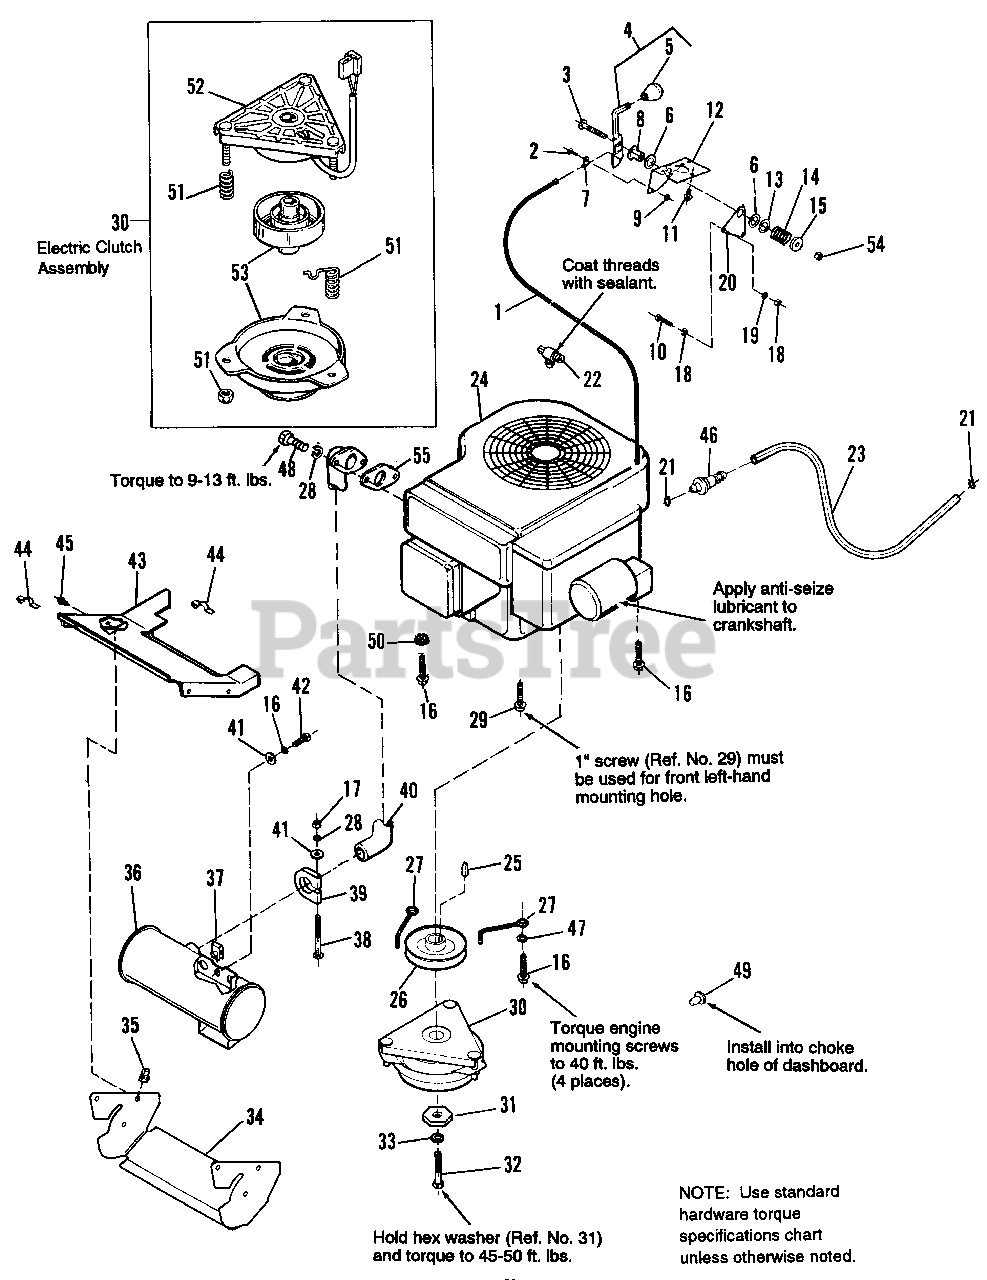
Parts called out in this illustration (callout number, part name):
1	CABLE, Throttle
2	SCREW, Trusshead, 10-32 x 1/2
3	CARRIAGE BOLT, 5/16-18 x 1-3/4
4	HANDLE, Throttle (Incl. Ref. No. 5)
5	KNOB, Throttle
6	WASHER, Nylon
7	CLIP, Bowden Wire
9	NUTASSY., 10-32
10	CAPSCREW, Hex, 1/4-20 x 1-1/2
11	SCREW, Plastite, 1/4-20 x 5/8
12	BRACKET, Throttle Mounting
15	WASHER, Plain, 5/16
16	SCREW, Hex, Washer Hd., Taptite, 3/8-16 x 1-1/2
17	NUT, Hex, Full, 5/16-18
18	NUT, Hex, Full, 1/4-20
19	LOCKWASHER, 1/4
20	PLATE, Spring
21	CLAMP, Hose
22	VALVE, Oil Drain
23	HOSE, Fuel, 38" Long
24	ENGINE, Briggs & Stratton
25	KEY, Hi-Pro
26	PULLEY ASSY.
28	LOCKWASHER, 5/16
29	SCREW, Hex, Washer Hd., Taptite, 3/8-16 x 1
30	ELECTRIC CLUTCH (Incl. Ref. Nos. 51-53)
31	WASHER, Hex
32	CAPSCREW, 7/16-20 x 2-1/2
33	LOCKWASHER, 7/16
34	DUCT, Lower Muffler
35	PAL NUT, 1/4-20
36	MUFFLER ASSY.
37	PAL NUT, 5/16-18
38	CARRIAGE BOLT, 5/16-18 x 2-3/4
39	CLAMP, Muffler
40	PIPE, Exhaust
41	WASHER, Plain, 5/16
42	CAPSCREW, Hex, 5/16-18 x 1
43	DUCT, Top, Muffler
44	CLIP
45	SCREW, Flange Whizlock, 1/4-20 x 5/8
46	FUEL FILTER
47	WASHER, Plain, 3/8
48	CAPSCREW, Soc. Hd., 5/16-18 x 3/4
49	FASTENER, Panel
50	LOCKWASHER External Tooth, 3/8
51	SPRING & NUT KIT
52	FIELD ASSY., Clutch
53	ROTOR & ARMATURE ASSY.
54	NUT, Hex, Esna Lock, 5/16-18
55	GASKET, Muffler
